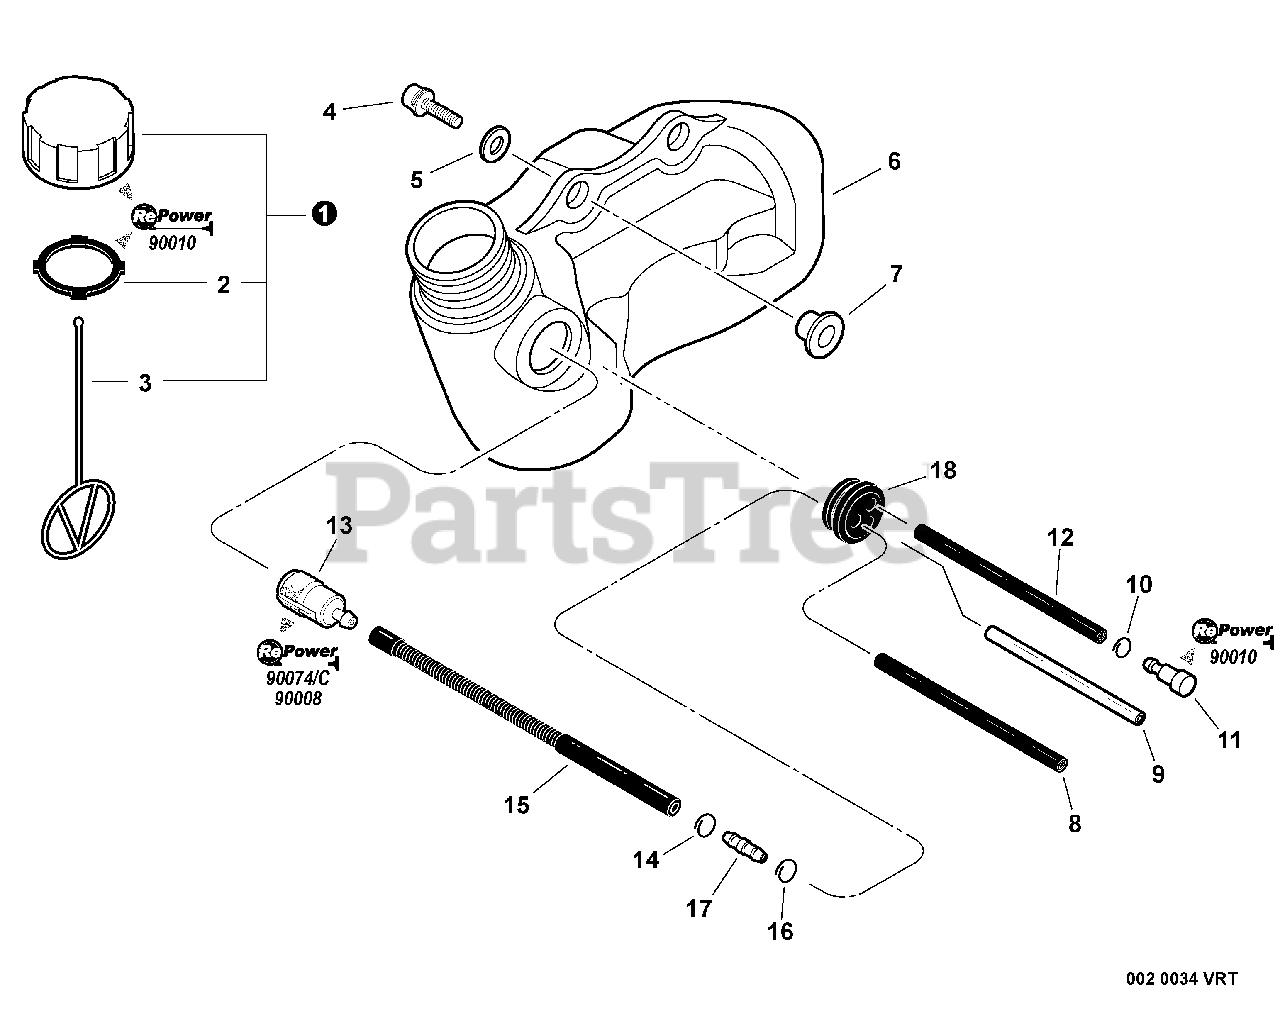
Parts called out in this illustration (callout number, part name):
1	CAP ASSY, FUEL
2	GASKET, FUEL CAP
3	CONNECTOR, CAP L= 123
4	BOLT 5×20
5	WASHER 5.5×12×0.8
6	TANK, FUEL
7	COLLAR 5
8	PIPE, FUEL 3×6×105 BLACK
9	PIPE, FUEL 3×6×75 CLEAR
10	CLIP 6.6 MM
11	VENT ASSY
12	PIPE - 3×5×65 -- BLACK
13	FILTER, FUEL
14	CLIP Ø6.5 MM
15	PIPE, FUEL 3×7×100 FLEXIBLE
16	CLIP 6 MM
17	CONNECTOR, PIPE
18	GROMMET, FUEL
19	FILTER KIT - REPOWER
20	CAP/VENT KIT - REPOWER
21	TUNE-UP KIT - REPOWER
